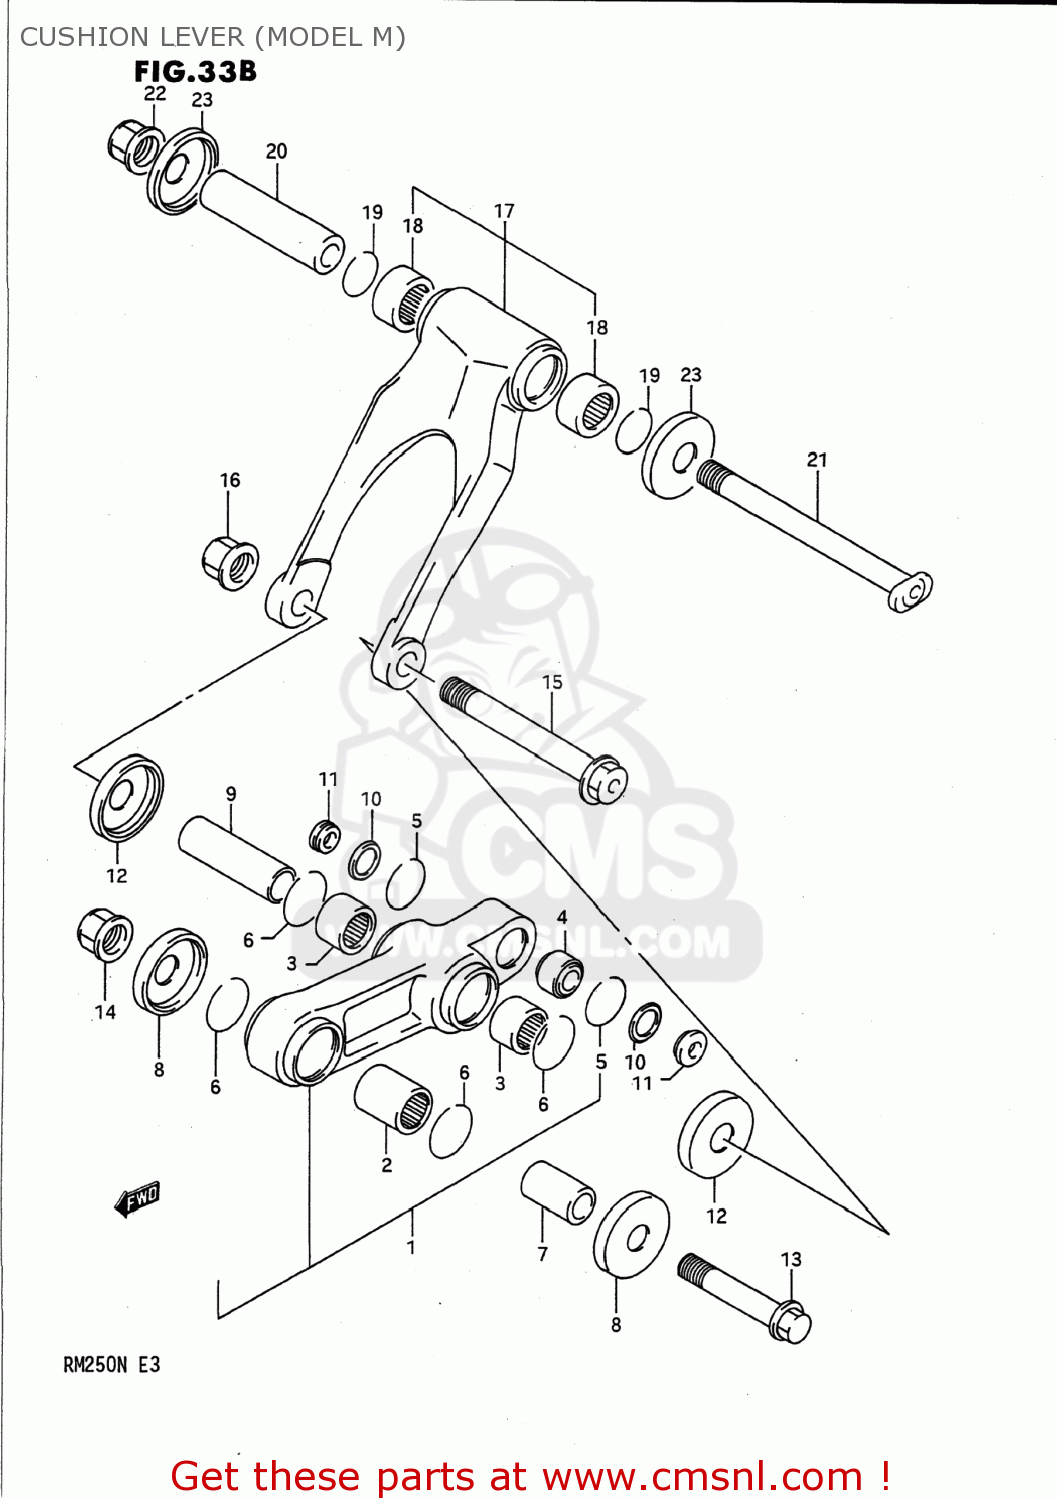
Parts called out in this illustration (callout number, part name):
1	LEVER SET,REAR CUSHION
2	BEARING(20X27X25)
3	BEARING(21X27X20)
4	BEARING,RR CUSHION LEVER
5	RING
6	CIRCLIP
7	SPACER,RR CUSHION LEVER FR
8	SEAL,REAR CUSHION LEVER
9	SPACER,REAR CUSHION LEVER,C
10	SEAL,RR CUSHION LEVER RR DUST
11	SPACER,RR CUSHION LEVER RR
12	SEAL,REAR CUSHION LEVER
13	BOLT,RR CUSHION LEVER FR
14	NUT 12MM
15	BOLT,REAR CUSHION LEVER,CENTER
16	NUT
17	LEVER SET,REAR CUSHION
18	BEARING(21X27X20)
19	CIRCLIP
20	SPACER,RR CUSHION ROD
21	BOLT,RR CUSHION ROD
22	NUT
23	SEAL,REAR CUSHION LEVER
